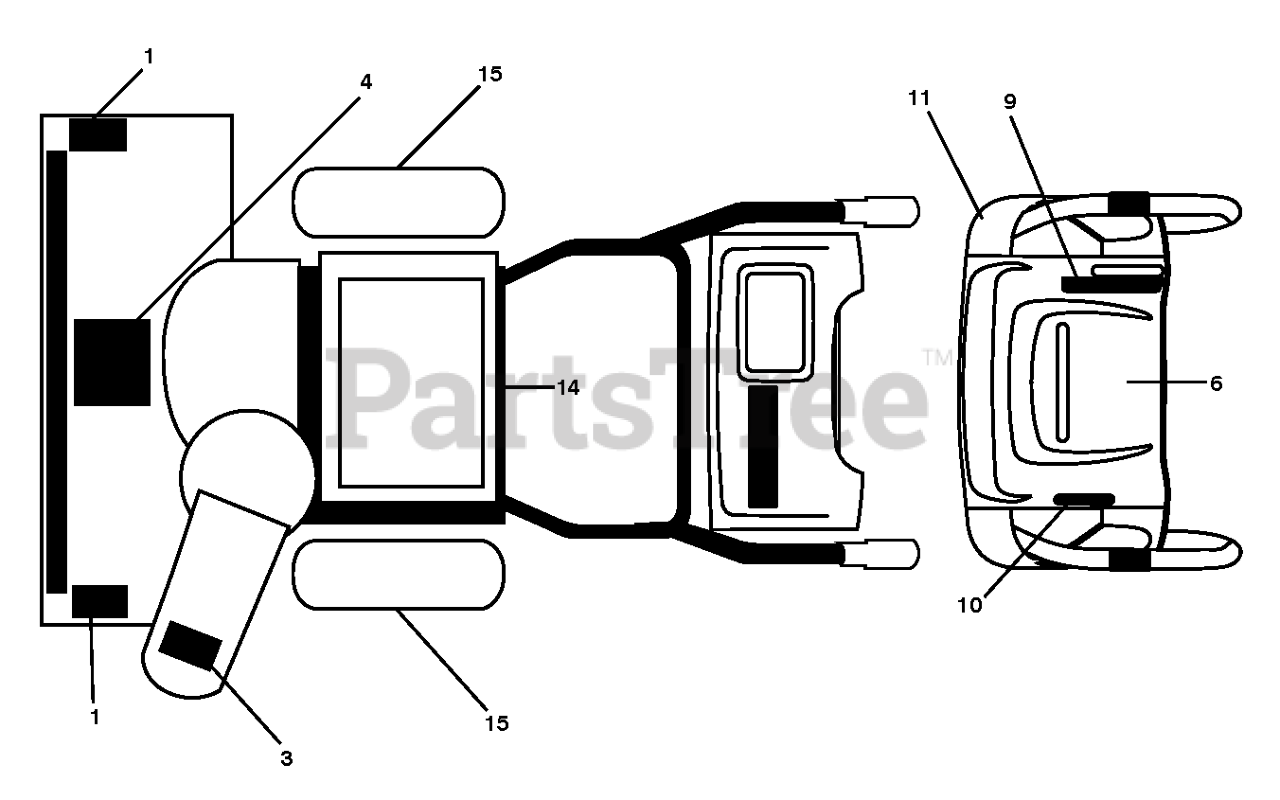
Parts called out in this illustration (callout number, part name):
1	DECAL.AUGER.SAFETY.
3	DECAL.CHUTE.SAFETY.
4	DECAL.AUGER."
9	DECAL CONSOLE DECAL DECAL.SNOW
10	DECAL CONSOLE DECAL DECAL.SNOW
11	DECAL.CONSOLE.HAND.WARMER
14	DECAL.FENDER
15	DECAL.BELT.GUARD.
